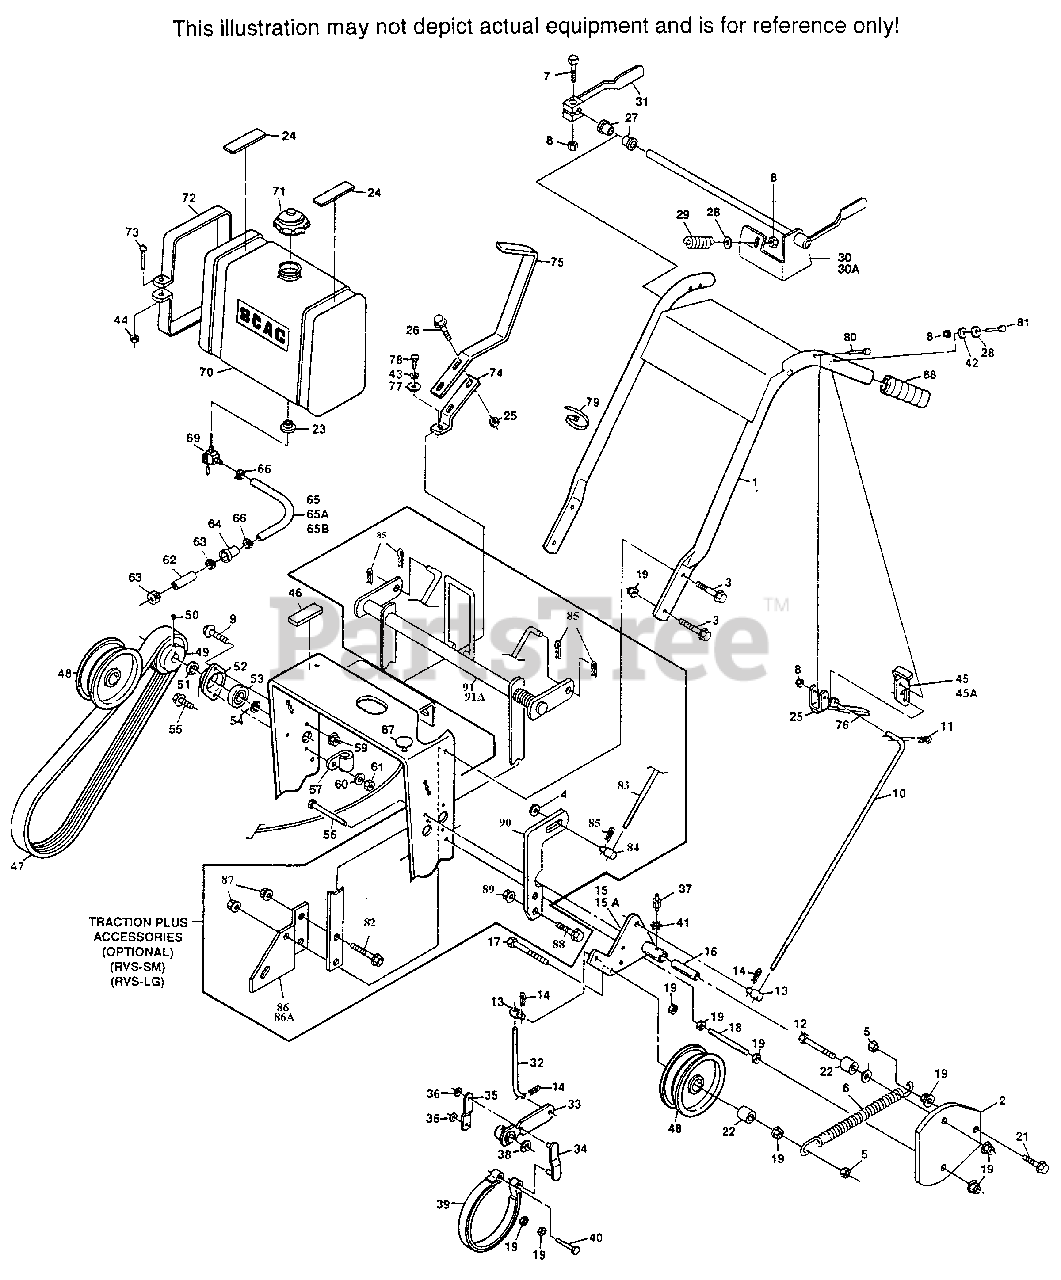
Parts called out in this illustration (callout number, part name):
1	HANDLE ASSEMBLY(FITS SW 52, 61, 72) INC.
2	BELT GUARD
3	CAPSCREW, 3/8-16 X 1" SERRATED FLANGE
4	WASHER, 3/8(25/64 X 15/16 X 12 GA.)
5	HEX NUT, 3/8-16 ELASTIC STOP
6	SPRING, IDLER
8	HEX NUT 5/16-18 ELASTIC STOP
9	CAPS, 1/4-20 X 3/4"
10	CONTROL ROD, STEERING
11	HAIR PIN, SMALL
13	SWIVEL JOINT
14	HAIR PIN, LARGE .094 DIAMETER
15	IDLER BRACKET, RH
15A	IDLER BRACKET, LH
16	IDLER SLEEVE
18	SUPPORT BELT GUARD
19	NUT, 3/8-16, SERRATED FLANGE
20	CAPSCREW, 3/8-16 X 2" SERRATED FLANGE
21	CAPSCREW, 3/16 X 1-1/4" SERRATED FLANGE
22	SPACER
23	BUSHING
24	RUBBER PADS,(UPPER)
25	STEERING LEVER
26	CAPSCREW, 5/16-18 X 1" SERRATED FLANGE
27	BUSHING
29	SPRING, OPERATOR'S PRESENCE
30A	OPERATOR'S PRESENCE LEVER, LH(LARGE FRAME)
31	OPERATOR'S PRESENCE LEVER, RH
32	BRAKE ROD
33	BRAKE LEVER
34	BRAKE LINK
35	BRAKE LINK PLATE
36	NUT, 3/8 PUSH-ON
37	GREASE FITTING, STRAIGHT, 1/4-28
38	RETAINING RING, 5/8 EXT.- "E"
39	BRAKE BAND
41	1/4" INTERNAL TOOTH LOCKWASHER
42	CURVED SPRING WASHER
43	LOCKWASHER, 1/4 SPRING
45	NEUTRAL LATCH, RH
45A	NEUTRAL LATCH, LH
46	RUBBER PAD(LOWER)
47	BELT, WHEEL DRIVE
48	IDLER PULLEY, WHEEL DRIVE
49	PULLEY, JACKSHAFT(INCLUDES 50)
51	SPACER, JACKSHAFT PULLEY
52	FLANGE, JACKSHAFT BEARING
53	BEARING, JACKSHAFT
54	RETAINING RING, 5/8 EXT. - BASIC
55	CAPSCREW, 1/4-20 X 1" SER. FLANGE
57	CLAMP
58	CAPSCREW, 5/16-18 X 3/4 SER. FLANGE
59	NUT, 1/4-20 SERRATED FLANGE
61	1/4-20 ELASTIC STOP NUT
66	CLAMP, FUEL HOSE
68	GRIP, HANDLE
69	VALVE, FUEL SHUT OFF
70	FUEL TANK ASSEMBLY(INCLUDES BUSHING & VALVE)
71	FUEL TANK CAP
72	STRAP, FUEL TANK
73	MACHINE SCREW, 1/4-20 X 2" ROUND HEAD SLOTTED
74	SHIFTER LEVER
75	SHIFTER LEVER EXTENSION
76	GRIP, STEERING LEVER
77	WASHER, 17/64 X 7/8 X 1/8 HT
78	HEX HEAD BOLT, 1/4-28 X 3/4 GRADE 8
79	CABLE TIE
82	CAPSCREW, 3/8-16 X 1", SER. FLNG.
83	ROD, TRACTION CONTROL
84	SWIVEL JOINT
85	HAIR PIN, LARGE .094 DIAMETER
86	MOUNTING BRACKET, TRACTION CONTROL, LH
86A	MOUNTING BRACKET, TRACTION CONTROL, RH
87	NUT, 3/8-16, SERRATED FLANGE
88	CAPSCREW, 5/16-18 X 3/4", SER. FLNG.
89	NUT, 5/16-18 SERRATED FLANGE
90	TRACTION LEVER, LH
90A	TRACTION LEVER, RH
91A	TRACTION LEVER WELMENT(LARGE FRAME)
